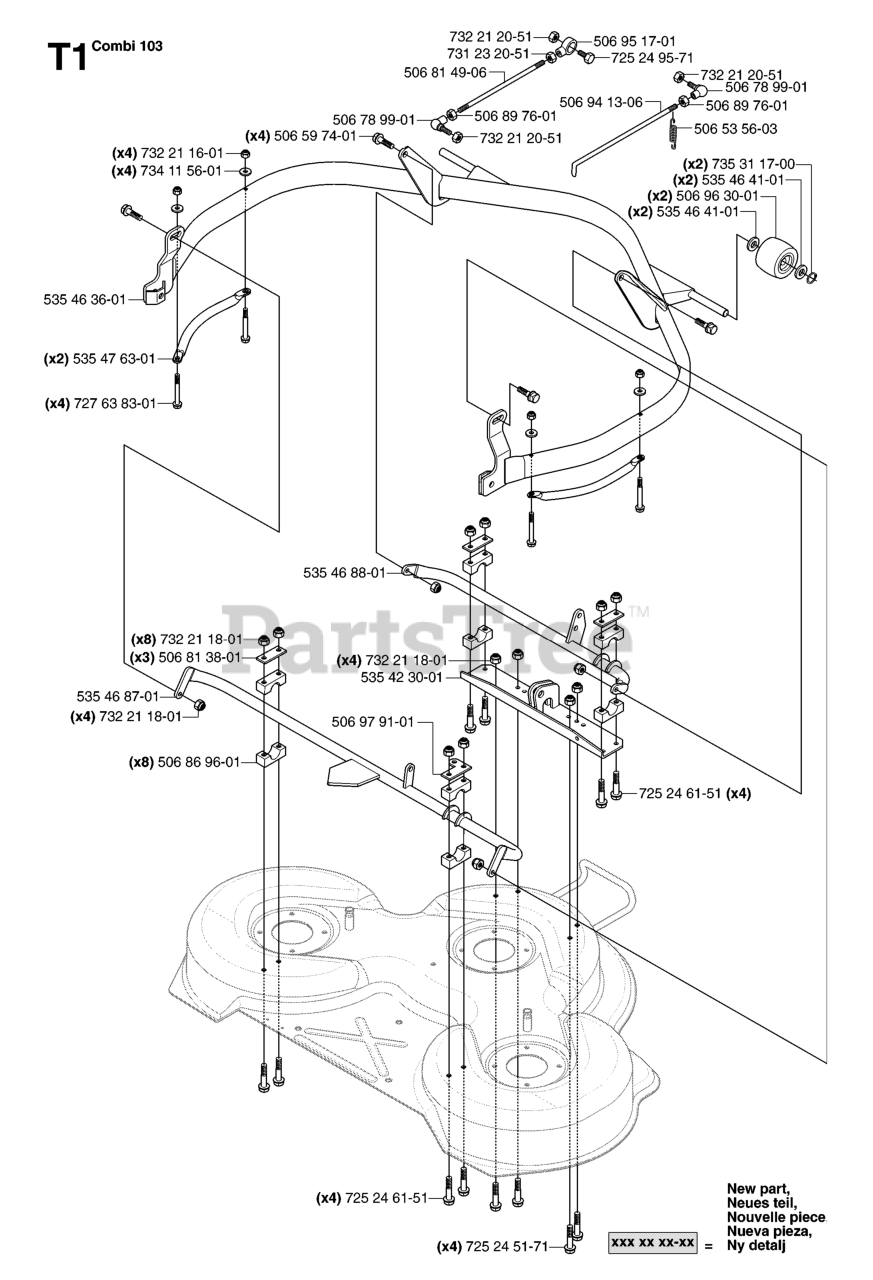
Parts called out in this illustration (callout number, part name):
1	SEAT, GRAY
2	SEAT PIVOT BRKT
3	BOLT
6	NUT
7	SPRING COMPRESSION
8	SCREW GTV
9	WASHER
10	PAN, SEAT
11	KNOB 1/2" YT
12	BRKT SWITCH
14	BOLT.ROUND.HEAD.SQUARE.NECK
15	SPACER SPLIT 28X.96
17	NUT T
18	CAP SPRING
21	BOLT SHOULDER 5/16-18
22	NUT.71038.31-18.HEX.NYLOCK
25	BOLT,SHOULD
